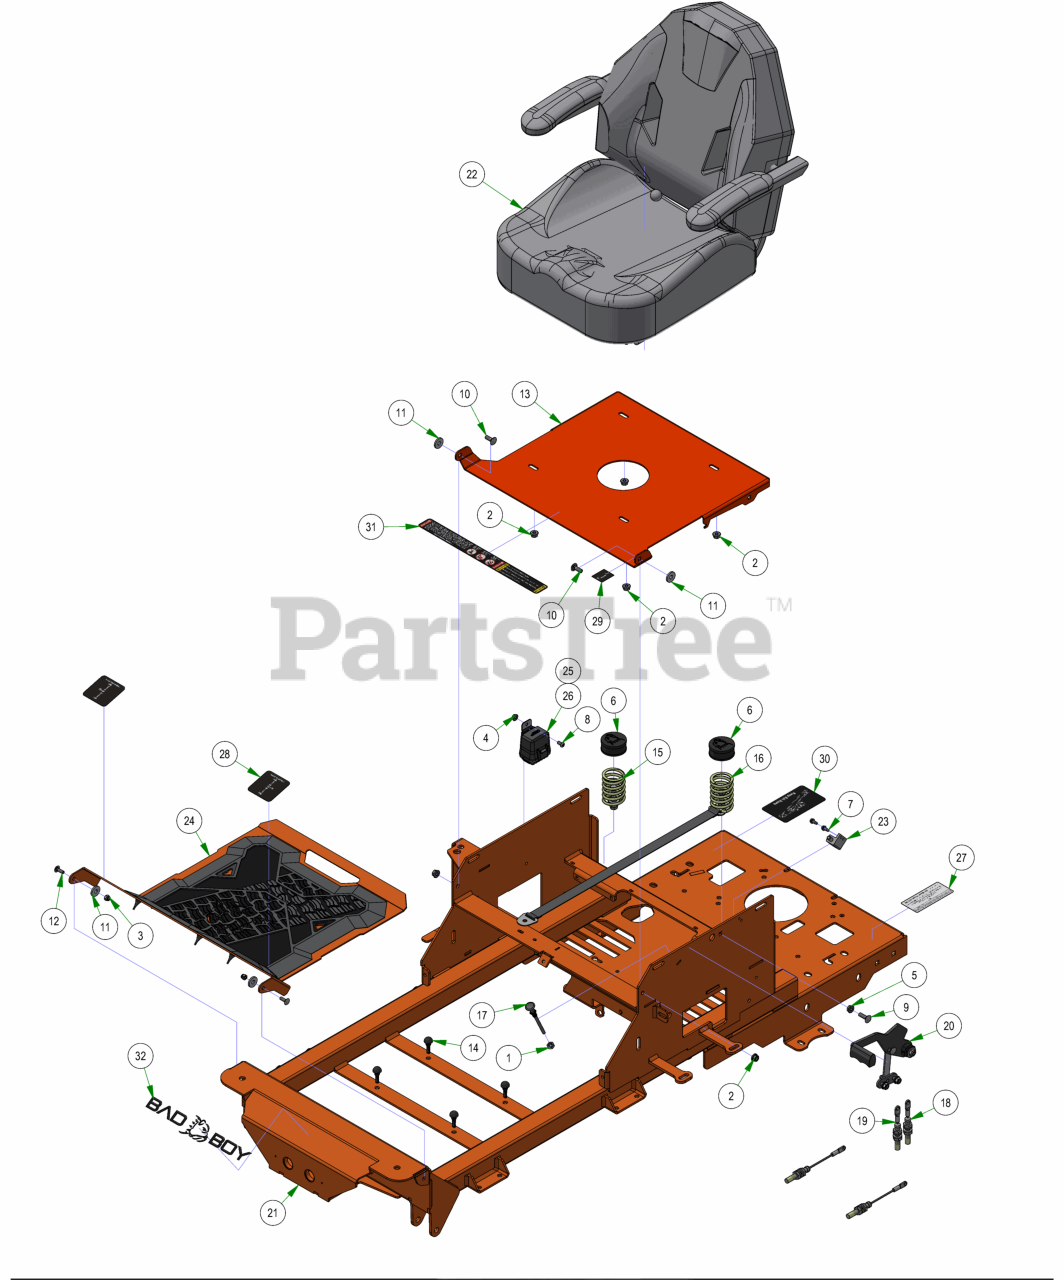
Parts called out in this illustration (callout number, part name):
1	3/8-24 HEX NUT ZINC YELLOW
2	5/16-18 NYLON INSERT FLANGE LOCKNUT ZINC
3	1/4-20 NYLON INSERT LOCKNUT ZINC
4	1/4-20 HEX SERRATED FLANGE NUT HARD/ZINC
5	5/16-18 HEX SERRATED FLANGE NUT HARD/ZINC
6	Spring Cap Cover
7	12-24 X 1/2 HEX WASHER UNLSOT F TCS ZINC
8	1/4-20 X 1/2 BUTTON SOCKET CAP SCREW 18-8 STAINLESS STEEL
9	5/16-18 X 1 CARRIAGE BOLT (GR.8) ZINC
10	5/16-18 X 7/8 CARRIAGE BOLT ZINC
11	.360 ID X .983 OD X .120 THICK FLAT WASHER NYLON
12	1/4-20 X 3/4 CARRIAGE BOLT (GR.5) ZINC
13	Seat Plate 2016
14	2023 Floor Board Rubber Bumper
15	Seat Spring Assembly
16	2022 Mav/HD seat spring assembly with strap
18	2021 Load Balanced Brake Cable 1
19	2021 Load Balanced Brake Cable 2
20	2021 Load Balanced Brake Handle Assembly
21	2025 ZT Elite Frame
22	2021 ZT Elite Seat
23	Safety Switch
24	2025 ZT/Mav/HD Floorboard Assembly
25	2024 Wiring Harness with Clips
26	2025 Wiring Harness with Clips and Lights
27	2025 EPA Build Date Punch Decal
28	2018 Maverick/2021 ZT Anti-Skid Steering Control Decals
29	2018 MZ/Magnum/ZT/MAV/Comp Out Brake Decal
30	Pump Belt Route Decal-Pump Plate
31	Outlaw Warning Decal
32	Flying Bulldog Front Bumper Decal
